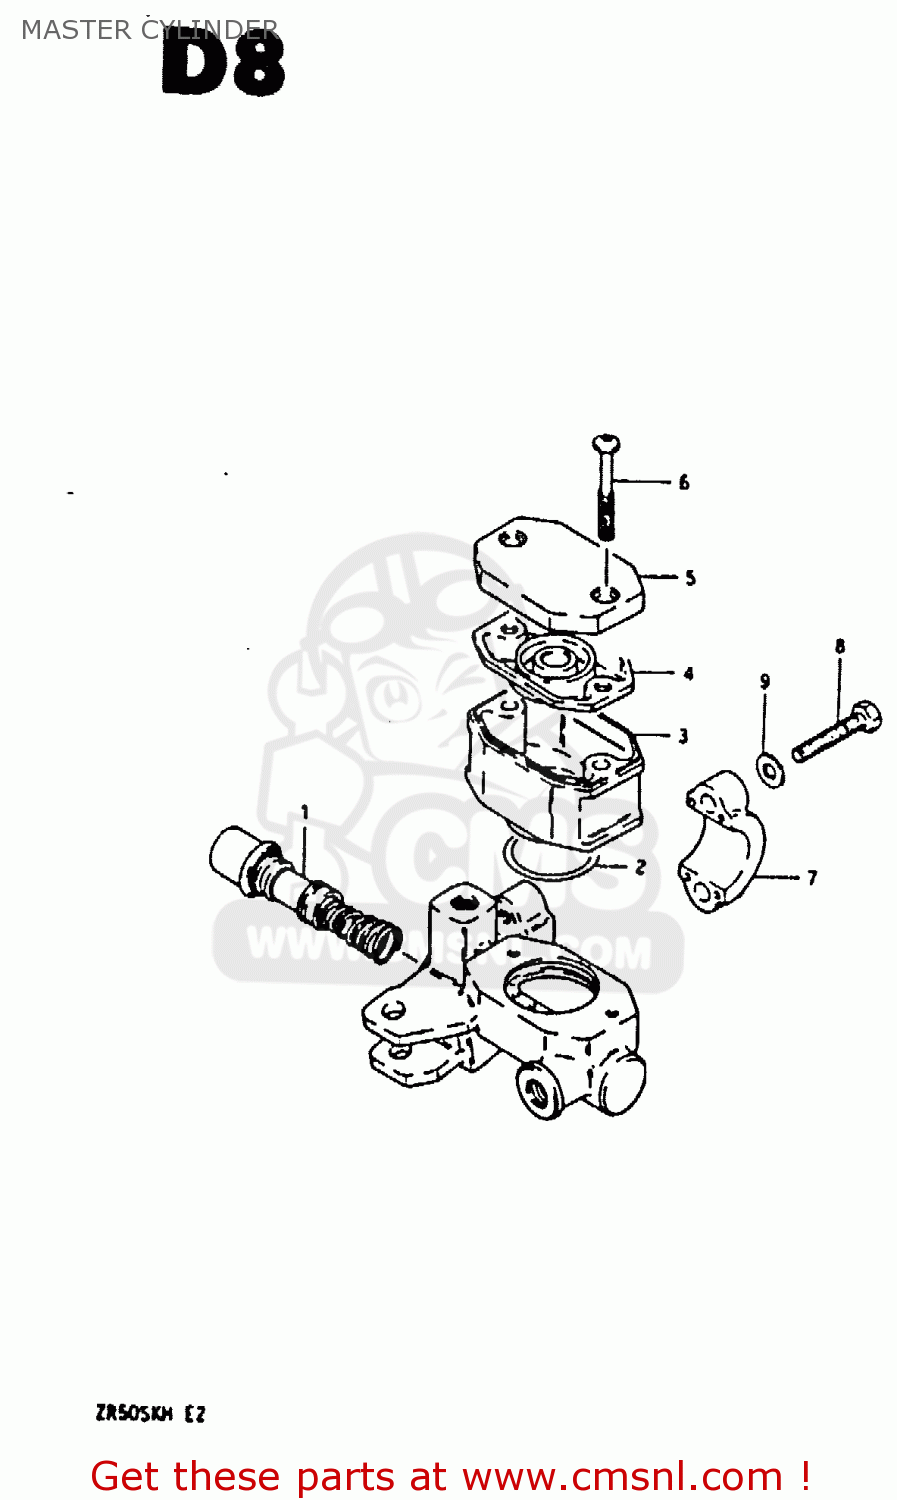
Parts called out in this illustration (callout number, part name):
1	PISTON & CUP SET
2	O RING
3	RESERVOIR
4	DIAPHRAGM
5	CAP,RESERVOIR
6	SCREW
7	HOLDER
8	BOLT
9	WASHER
